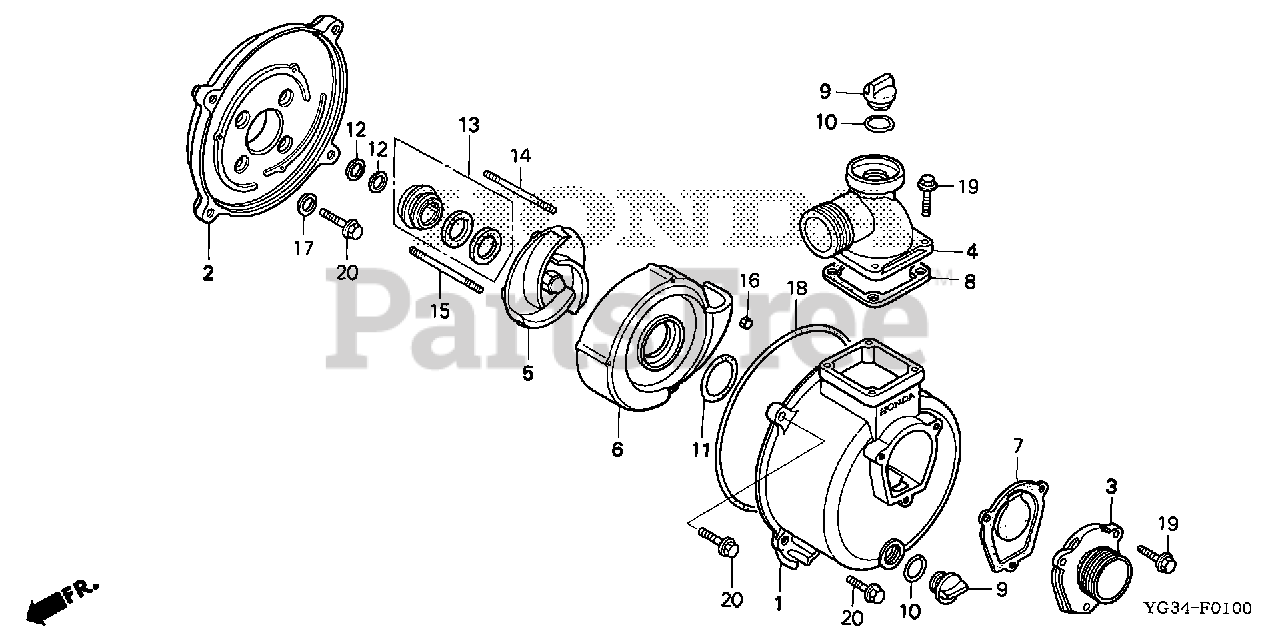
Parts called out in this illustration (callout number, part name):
2	COVER, CASING
3	INLET (NPTF)
4	OUTLET (FOR U.S.A.) (NPTF)
6	CASE, VOLUTE
7	VALVE, IN.
8	GASKET, OUTLET
9	CAP, FILLER
10	RING, SEAL (B)
11	O-RING (49X5.7) (NOK)
12	SHIM, ADJUSTER
13	SEAL, MECHANICAL
14	BOLT, STUD (6X50)
15	BOLT, STUD (6X50)
16	NUT, CAP (6MM)
17	WASHER, SEALING (8MM)
18	O-RING (217.5X3.5) (ARAI)
19	BOLT, FLANGE (8X25)
20	BOLT, FLANGE (8X28)
